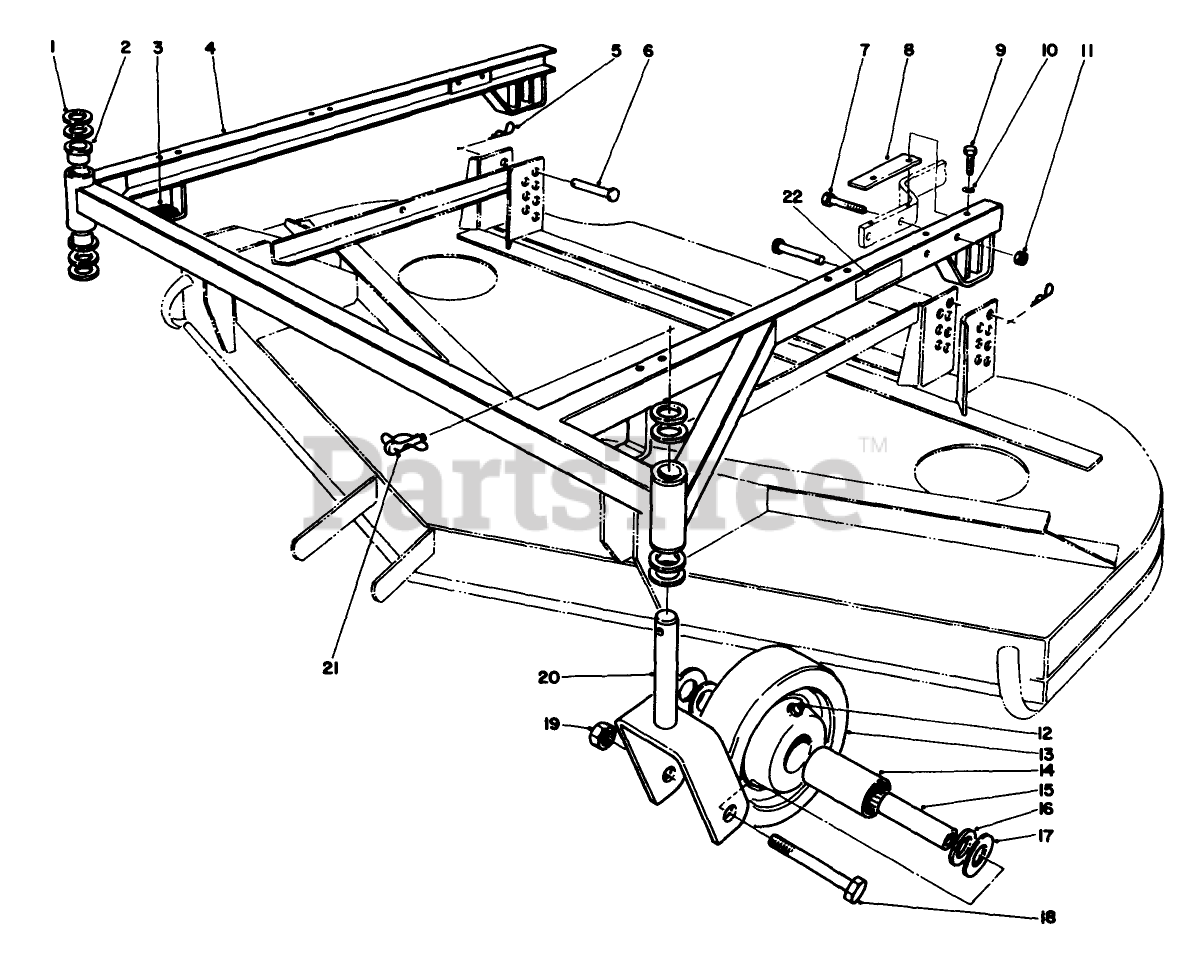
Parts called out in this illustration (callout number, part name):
1	WASHER-THRUST
2	Bushing
3	Pad-Rubber
4	Suspension Frame (Incl. Ref. #2)
5	PIN-HAIR
6	PIN-CLEVIS
7	SCREW-HH
8	SHIM-CARRIER
9	SCREW W/PATCH
10	WASHER-FLAT
11	NUT-LOCK, CONE
12	FITTING-GREASE
13	WHEEL
14	ROLLER BEARING
15	SPANNER BUSHING
16	BEARING RETAINER
17	THRUST WASHER
18	SCREW-HH
19	NUT-HEX
20	FORK-Castor
21	PIN-LYNCH
22	DECAL-HOC, LH
